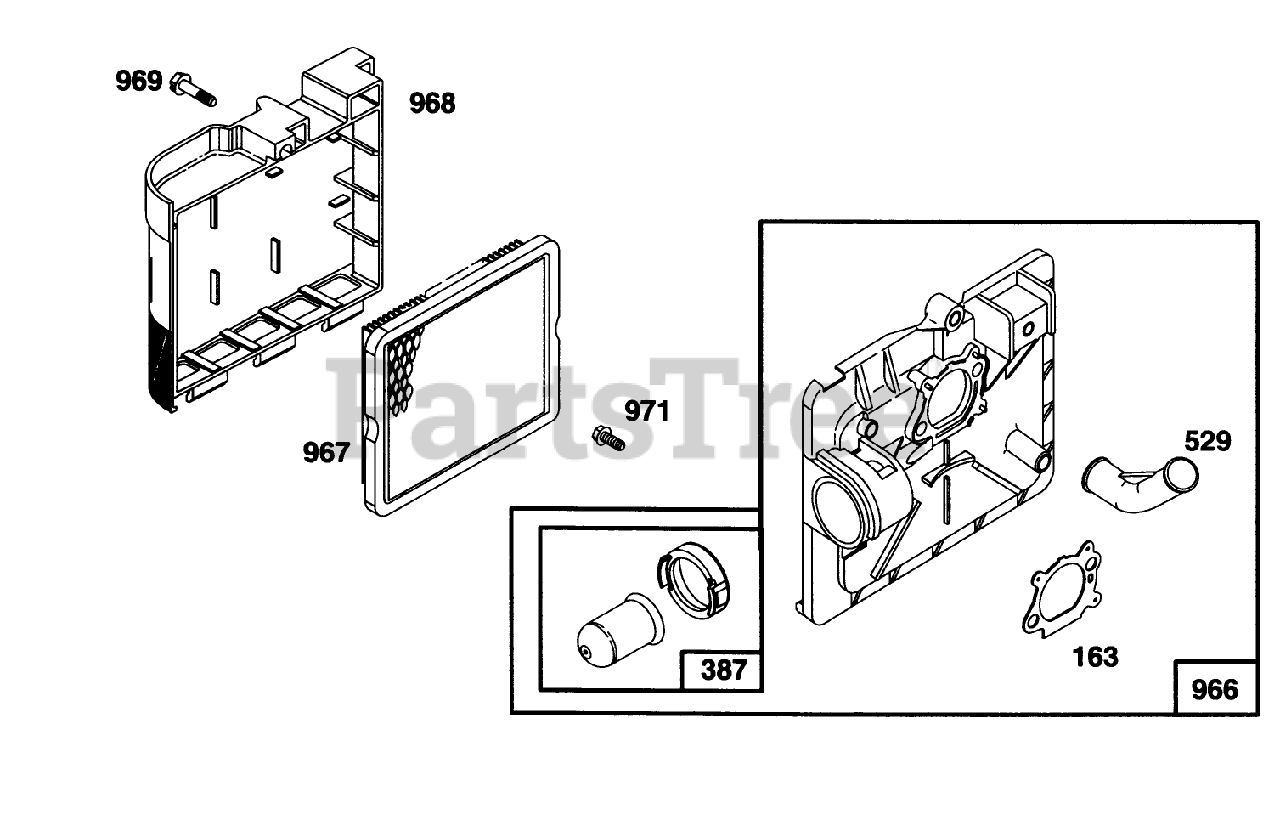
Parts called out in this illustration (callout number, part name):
163	Gasket-Cleaner, Air
387	CarburetorPrimer
529	Grommet
966	Base-Primer, Air Cleaner
967	Filter-Air Cleaner, Cartridge
968	Air Cleaner Cover
969	Screw-Cover Mt.
971	Screw-Air Cleaner
